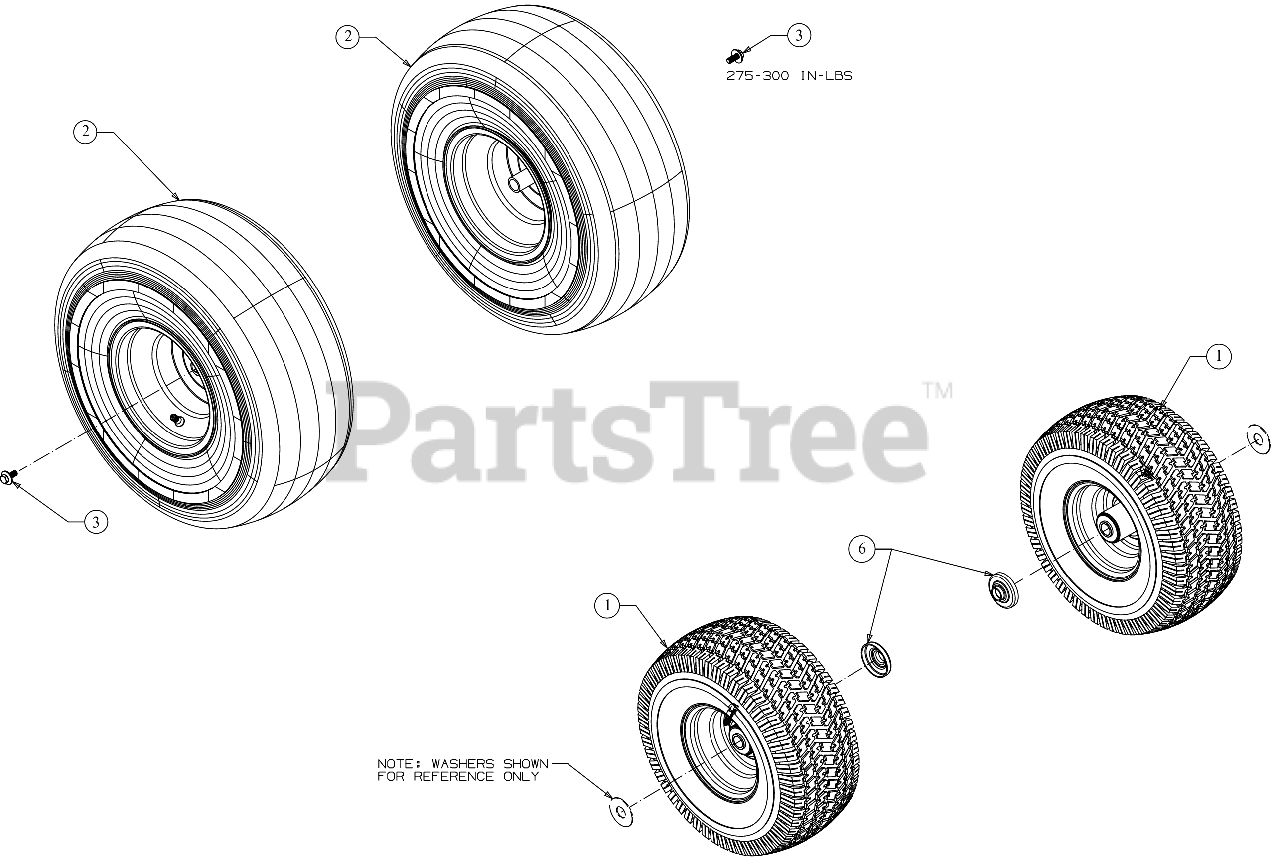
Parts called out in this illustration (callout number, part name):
1	WHEEL ASSEMBLY (15X6X6) (BEIGE-CARLISLE)
2	WHEEL ASSEMBLY (20X8X8) (BEIGE-CARLISLE)
2	TIRE-MULTI TRAC 20X10X8 CAR
3	SCREW 5/16-24 x .85 GR5
6	WHEEL BEARING COVER
